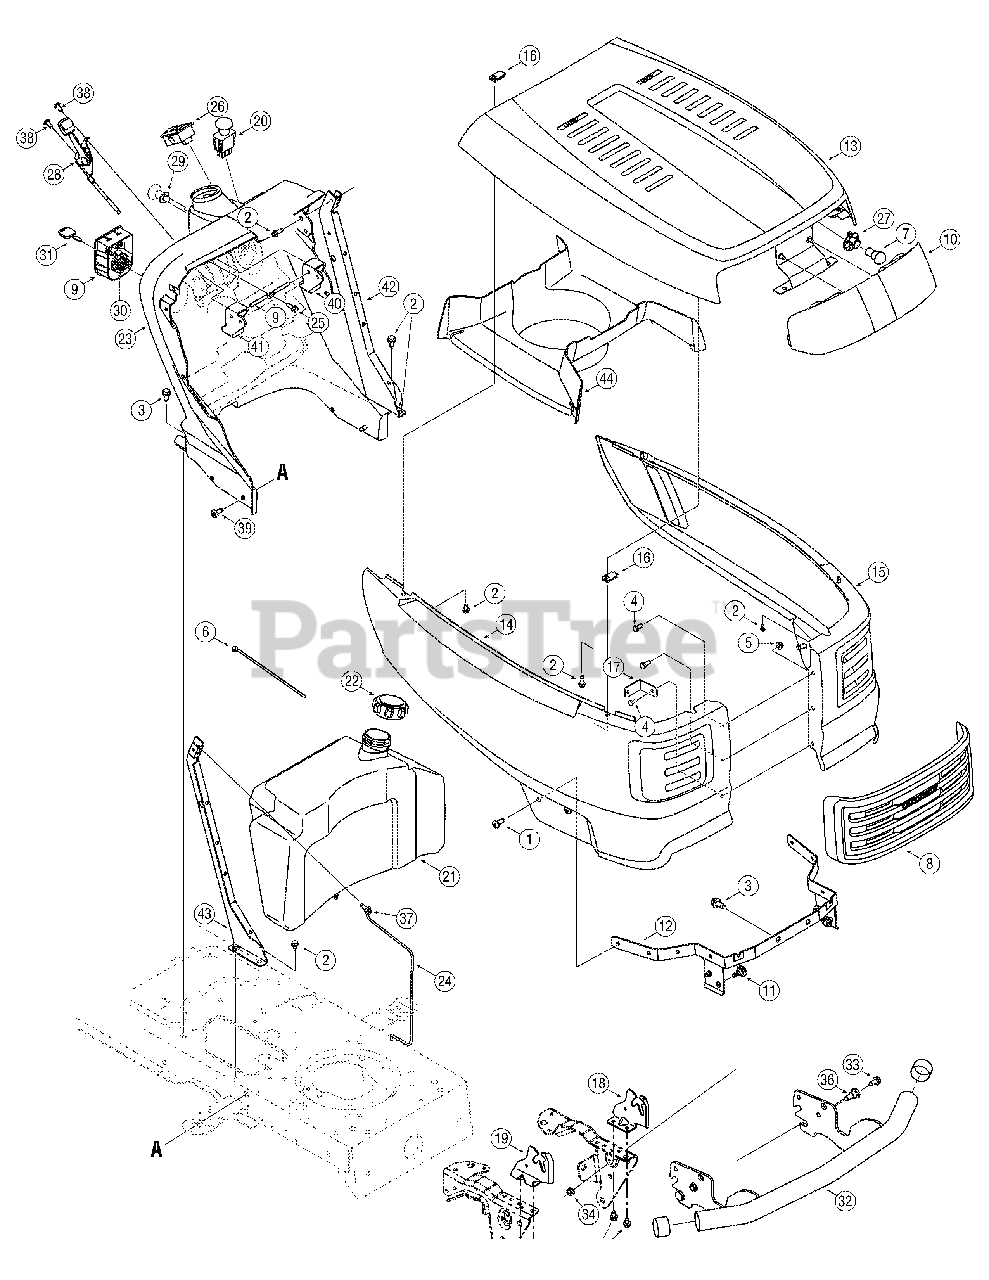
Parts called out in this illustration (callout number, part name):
1	Screw, 5/16-18, .375
2	Screw, 1/4-20, 0.500
3	Screw, 5/16-18, 0.500
4	Screw, 1/4-20, 0.620
5	Flange Lock Nut, 1/4-20
6	Cable Tie, 3/16 x .05 x 7.4
7	Headlamp, 12V
8	Troy-Bilt Grill Insert
9	Bent Lever Rod
10	Troy-Bilt Lens
11	Screw, Shldr, .43 x .29, 5/16-18
20	Electric PTO Switch
21	Fuel Tank, 3 gal. TB
22	Fuel Tank Cap
23	Dash Panel
24	Gas Tank Support Rod
25	Screw, 1/4-15, .750
26	Hour Meter Indicator
27	Lamp Socket
28	Throttle Control, 39.0 Lg.
29	Choke Control
30	Module, Ignition Switch
31	Key
31	Key w/ Plastic Grip
33	Screw, 5/16-12, 0.750
34	Flange Lock Nut, 3/8-16
35	Bumper Cap
36	Shoulder Bolt, 3/8-16
37	Screw, 1/4-20, 0.750
38	Screw, 1/4-14, 0.625
39	Screw, 5/16-18, 0.750
40	Dash Brake Lever
41	Dash Cruise Lever
